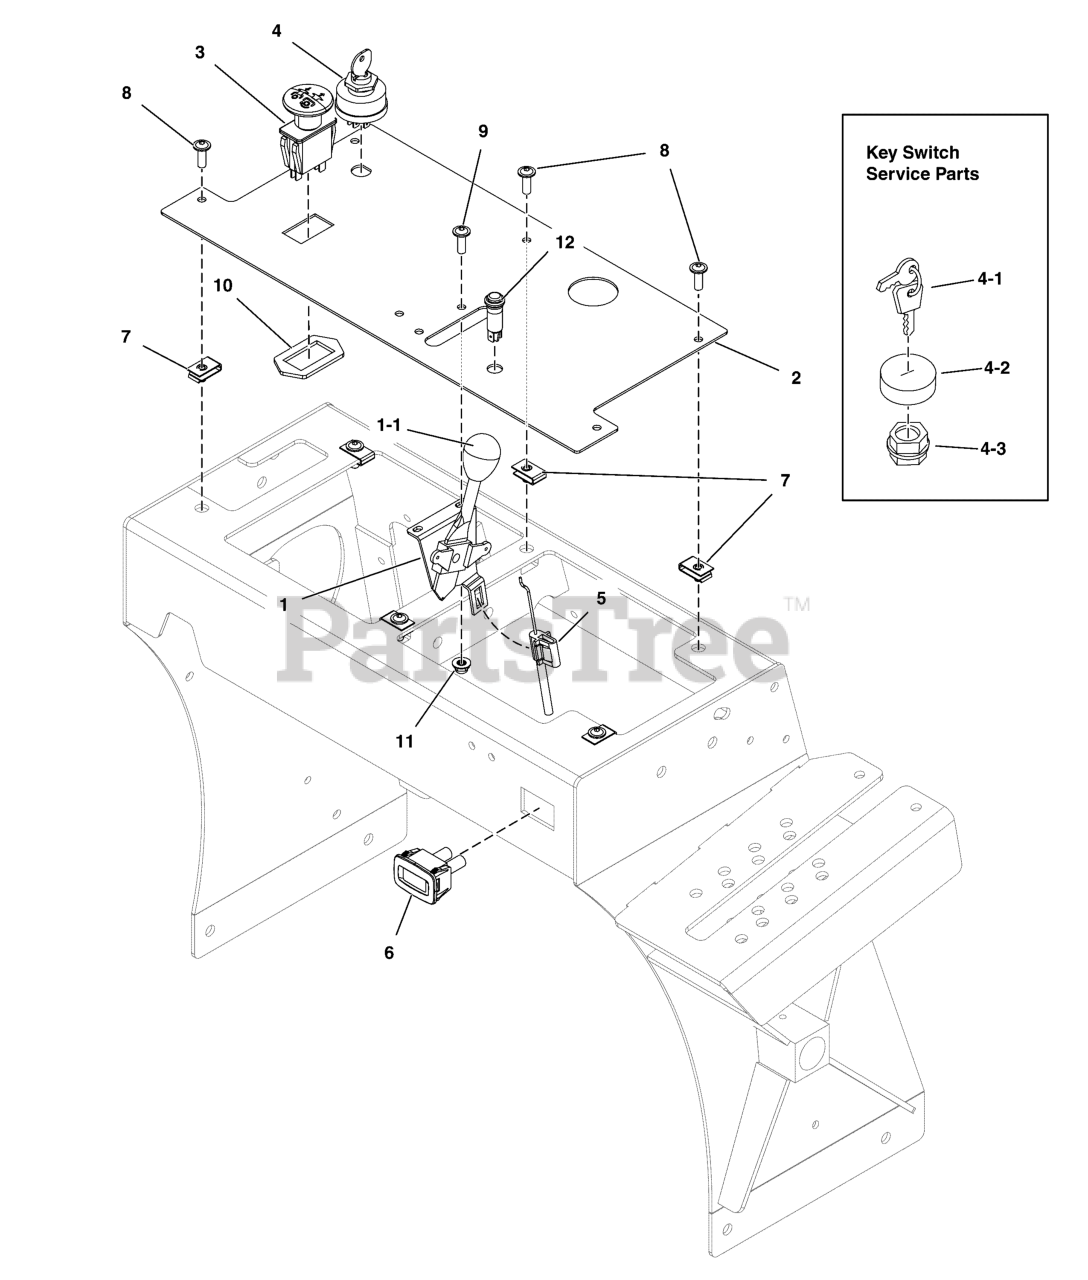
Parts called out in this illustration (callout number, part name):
1	LEVER, HEAVY DUTY, THROTTLE CONTROL
1-1	THROTTLE CONTROL HANDLE/KNOB
2	DASH PANEL W/DECALS, SRSZ2EFI (5417475A)
3	PTO SWITCH, MOMENTARY, SMALL KNOB
4	SWITCH, IGNITION, 6 POST
4-1	KEY, IGNITION MOLDED SET
4-2	COVER, PLASTIC, SNAP ON
4-3	PLASTIC NUT
5	CABLE, THROTTLE, 40"
7	BODY CLIP, 1/4-20 X 1/2" DEEP
8	SCREW, FLANGE, ALLEN HD, 1/4-20 X .75 SS
9	SCREW, #10-24 X 1/2" ROUND PHILLIPS
10	RING, SWITCH RETAINER
11	NUT, Hex, Nylon Lock, #10-24
12	LIGHT, INDICATOR, PANEL, LED, RED
